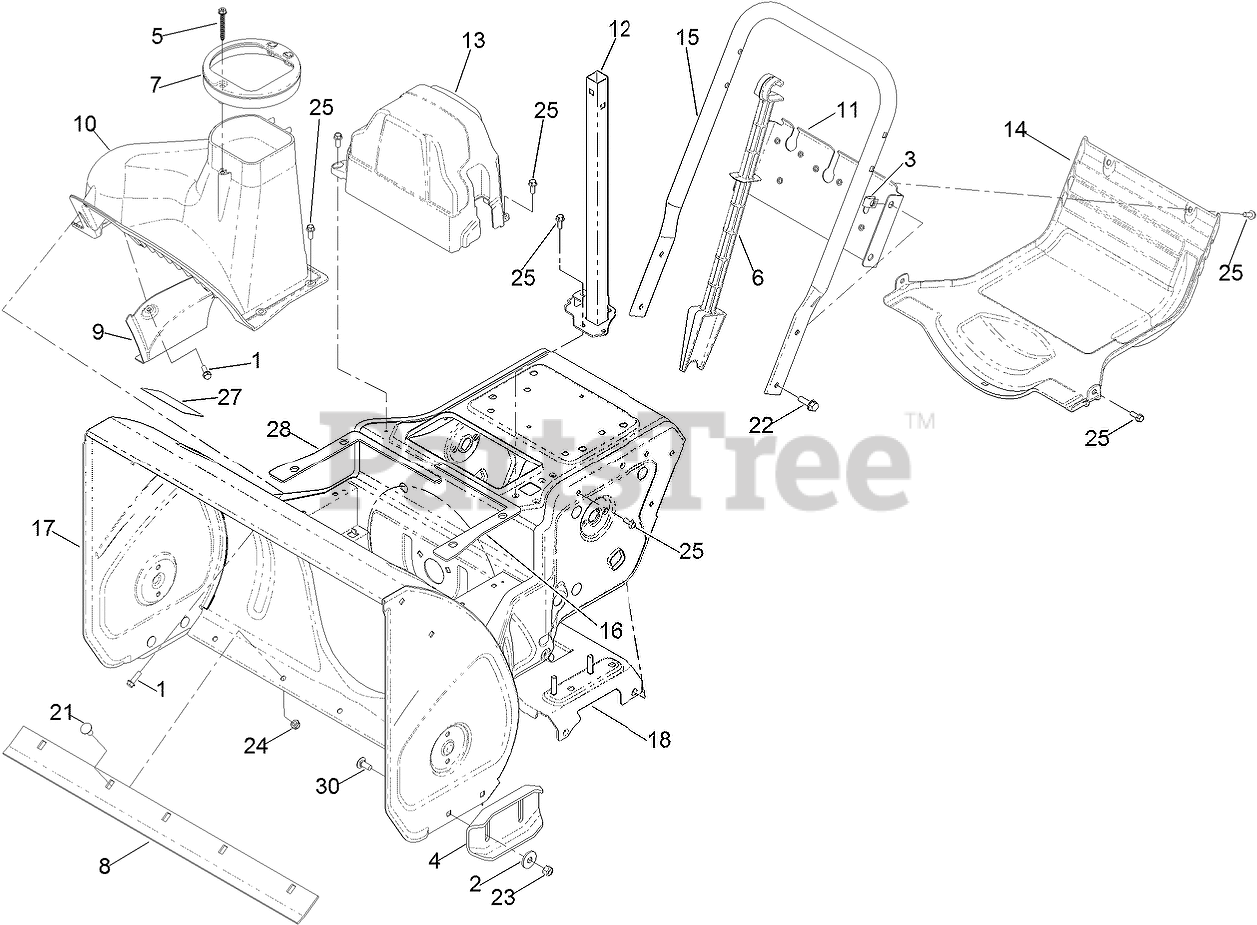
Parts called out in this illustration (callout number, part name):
1	SCREW-PLASTITE, HWH
2	WASHER-FLAT
3	NUT-U
5	SCREW-HWH, PLASTITE
6	STICK-CLEANOUT
7	GUIDE-CHUTE
8	SCRAPER-26 INCH
9	COVER-LINER
11	BRACE-FRAME
12	SUPPORT-CHUTE
13	COVER-BELT
14	COVER-LOWER
15	HANDLE-LOWER
16	SEAL-HOUSING, LH
17	FRAME ASM
18	PLATE-STUD ENGINE
21	BOLT-CARR
22	SCREW-HHF
23	NUT-HEX
24	NUT-HEX
25	SCREW-HWH
27	DECAL-DANGER, AUGER
28	SEAL-HOUSING, RH
30	BOLT-CARR
